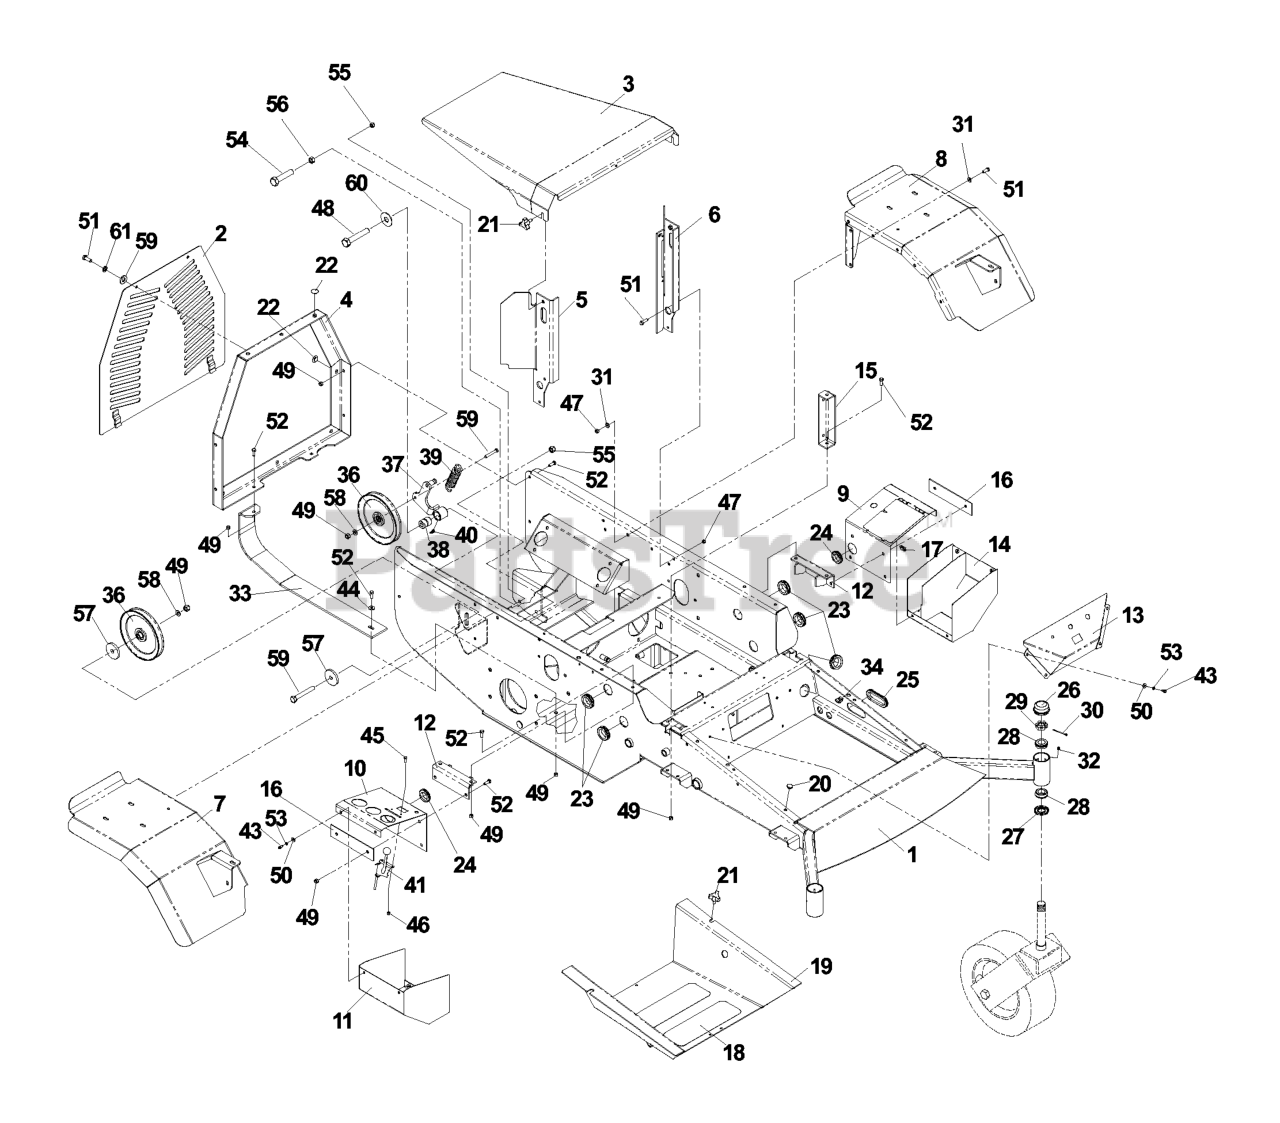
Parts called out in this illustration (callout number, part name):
1	FRAME W/DECALS
2	PANEL W/ DECALS
3	HOOD ORANGE
4	REAR FRAME
5	SUPPORT WLDMT, RT
6	SUPPORT WLDMT, LT
7	FENDER WELDMT, RH
8	FENDER WELDMT, LH
10	CONSOLE TOP-PAINTED
11	CONSOLE BOTTOM
12	MTG ANGLE WELDMT
13	CENTER CONSOLE WELDMENT
14	BOTTOM CONSOLE
15	SUPPORT WELDMENT
16	BLACK-STIFFNER-PAINTED
17	MAGNETIC LATCH
18	ANTI-SKID PAD
19	FOOT PLATE WIDMT
20	GROMMET, BUMPER
21	KNOB W/STUD
22	GROMMET BUMPER
26	GREASE CAP
28	TAPERED ROLLER BRG
29	NUT 1"C HEX SLOTTED
30	COTTER PIN 1/8 X 2
31	FLAT WASHER 5/16 SAE
32	ZERK
33	SKID PLATE
34	U-CLIP 5/16-18 NUT RETAINER
36	IDLER PULLEY
37	ARM WELDMENT
40	ZERK
41	THROTTLE CONTROL W/BALL KNOB
43	SCREW 1/4 X 5/8
44	WASHER 3/8 FLAT
45	HCS #10-24 X 1/2
46	NUT 10-24 NYLOC
47	NUT 5/16 NYLOC
48	HEX SCREW 1/2-13 X 2.5" GR 5
49	NUT 3/8-16 NYLOC
50	WASHER 1/4 FLAT
51	HCS 5/16C X 1
52	HCS 3/8-16X1.GRD.5.ZD
53	LOCKWASHER 1/4"
54	HCS 1/2-13X2 GR 8
55	NUT 1/2-13 HEX NYLOC ZD
56	NUT HEX 1/2
57	SPINDLE WASHER
58	WASHER 3/8 SAE FLAT
59	WASHER 5/16 FLAT
60	WASHER 1/2 FLAT
61	WASHER.LOCK.HVY.HLCL.SPR.5/16
